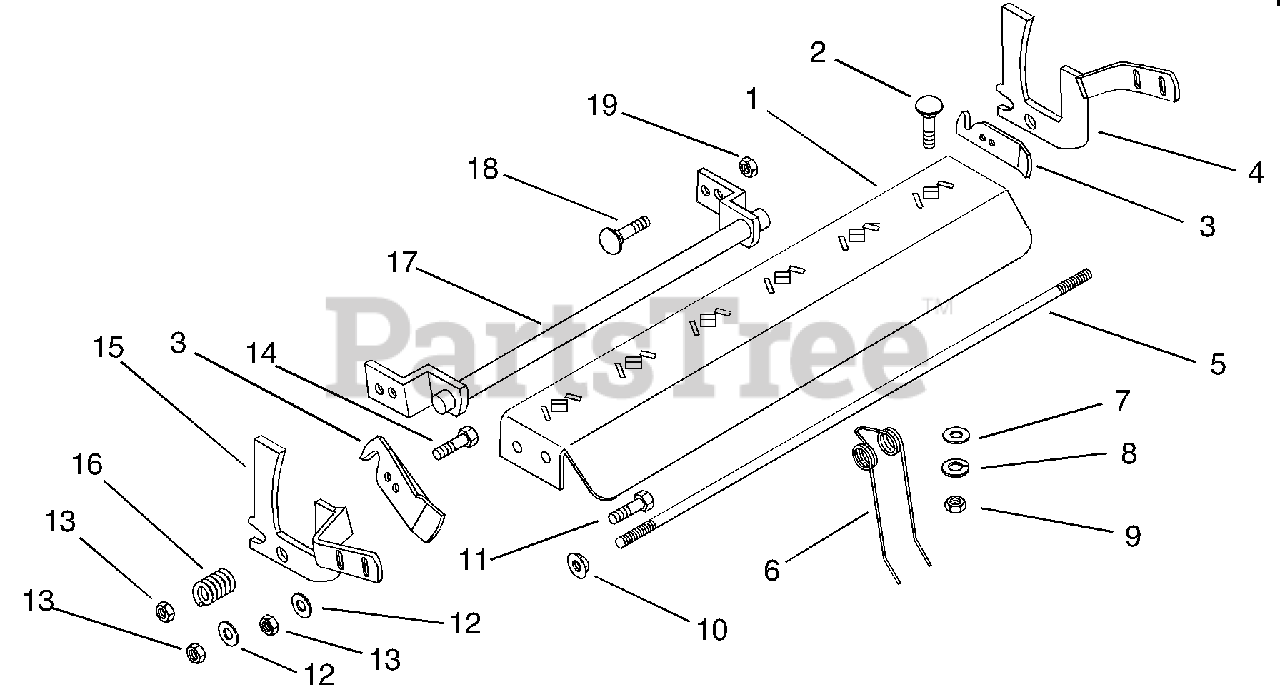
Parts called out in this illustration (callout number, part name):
1	Tine Plate
2	Bolt-Round Head Square Neck .31-18 x .75 Grade 2
4	Cam Bracket-Left Hand
5	Rod, Retention
7	Washer-Flat-Steel .328 x 1.0 x .094
8	Washer-Locking .312 x .097
9	Nut-Hex .31-18
10	Nut-Locking-Flange .250-20
11	Bolt-Hex .25-20 x 1.25 Grade 5
12	Washer-Flat-Steel .281 x .62 x .065
13	Nut-Locking-Center .25-20
14	Bolt-Hex .25-20 x 1.25 Grade 5
15	Cam Bracket-Right Hand
16	Spring-Compression .058 x .68 x .75
17	Dethatcher Retainer Weldment
18	Bolt-Round Head Square Neck .31-18 x .62
19	Nut-Locking-Center .31-18
